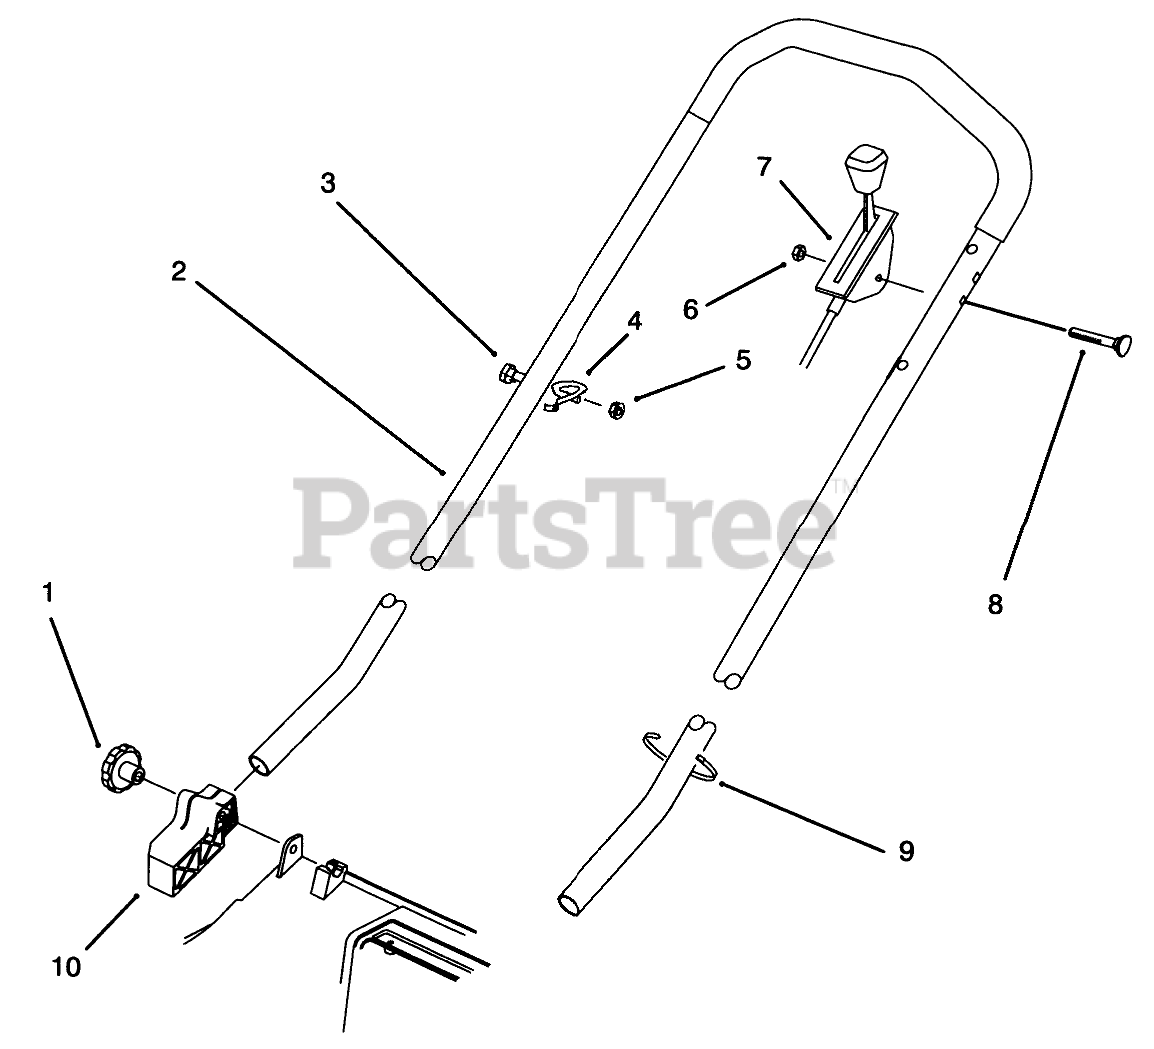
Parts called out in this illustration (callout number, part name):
2	HANDLE (DIPPED)
3	SCREW-HH
4	GUIDE-ROPE
5	NUT-LOCK, NI
6	NUT-LOCK, NI
7	THROTTLE CONTROL
8	SCREW-HANDLE
9	TIE-CABLE
10	MOUNT-HANDLE, RH
